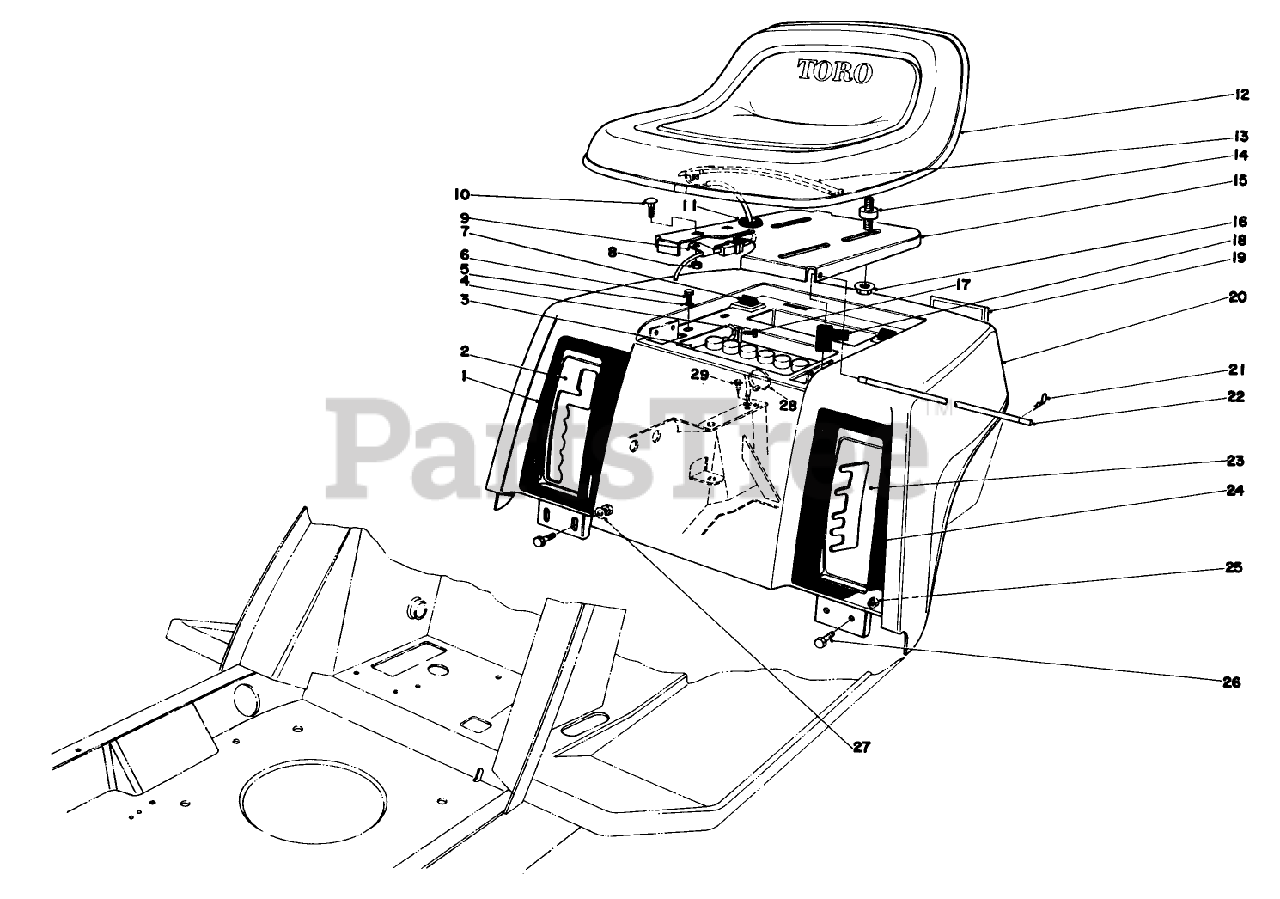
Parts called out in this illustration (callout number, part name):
3	SEE SB MISC 14
4	NUT-WING
6	SCREW-THD ROLL, HWH
8	NUT-KEPS
10	SCREW-CARR
11	GROMMET
13	SWITCH-SEAT
14	ISOLATER-SEAT
16	NUT-HF
17	SCREW-HH
18	BOOT-TERMINAL
19	REFLECTOR
22	PIVOT-SEAT
25	NUT-LOCK, NI
26	SCREW-HH
27	WASHER-PLAIN
28	TIE-CABLE
29	SCREW-HWHTF
